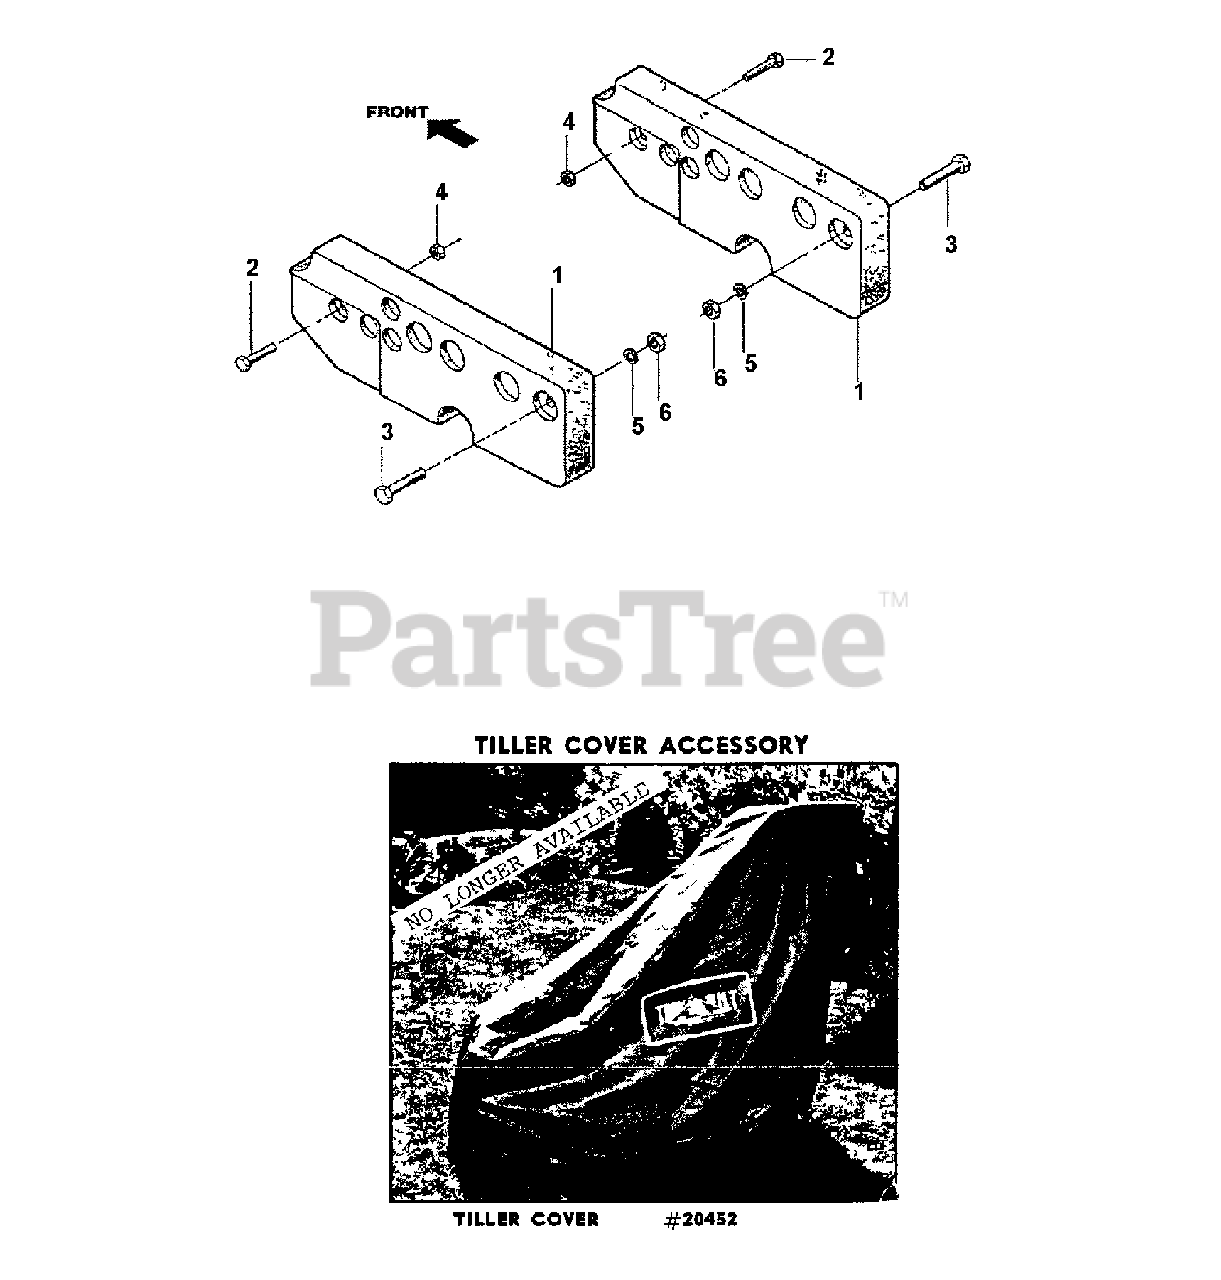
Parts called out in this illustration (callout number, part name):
1	Frame Weight
2	Hex Screw, 1/4-20 x 1-1/4
3	Hex Screw, 5/16-18 x 1-1/2
4	Hex Nut, 1/4-20
5	Lockwasher-5/16
6	Hex Nut, 5/16-18
